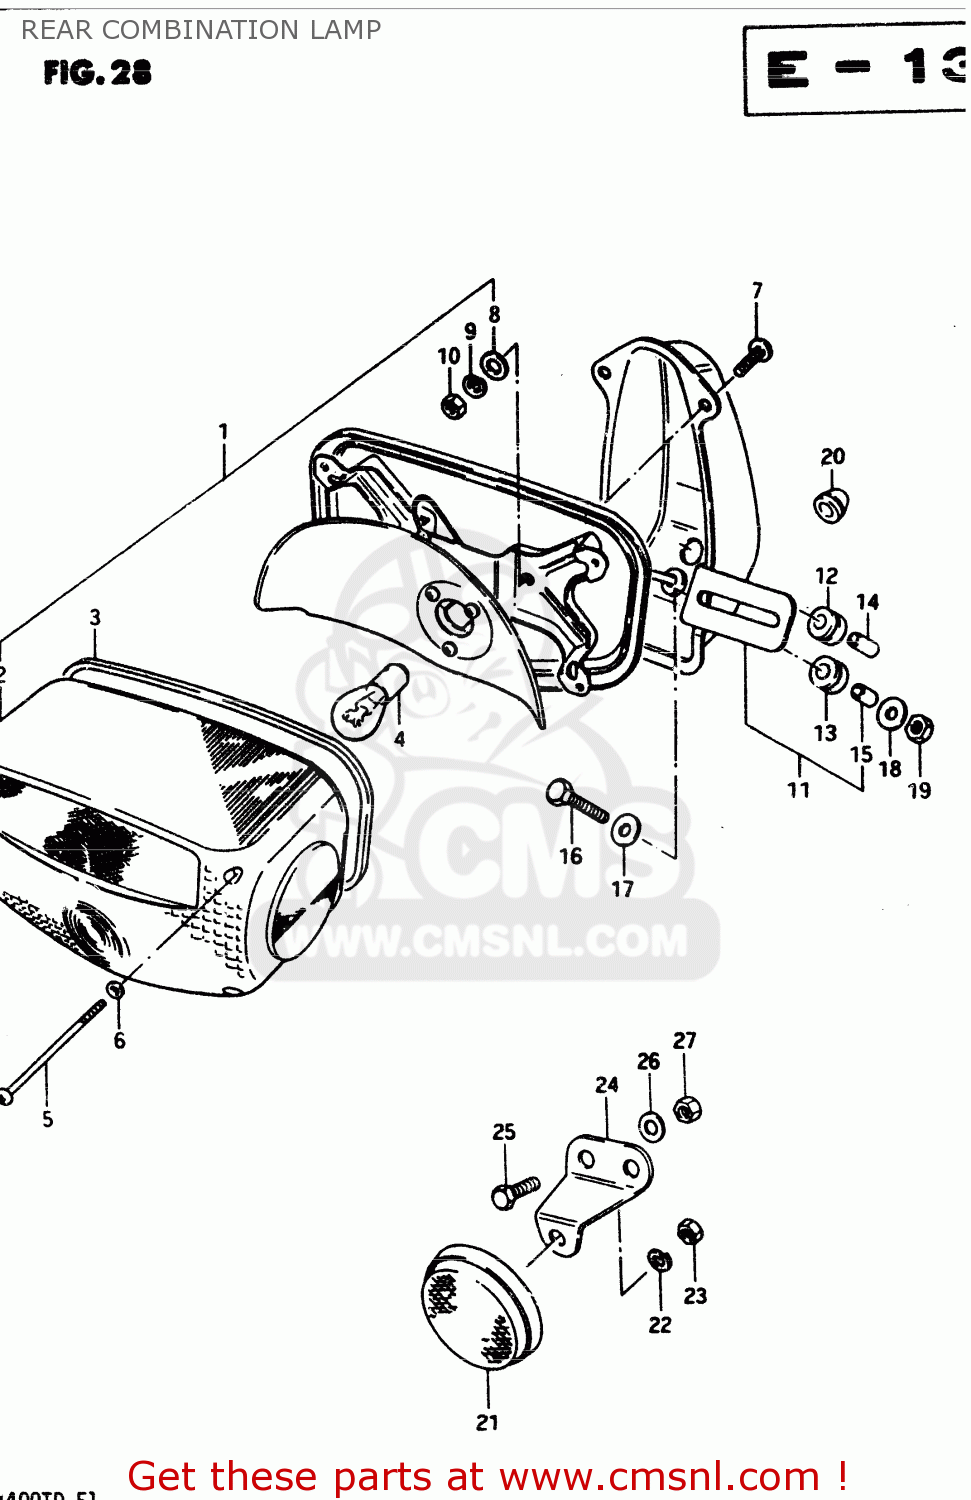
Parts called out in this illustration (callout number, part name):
1	LAMP UNIT, TAIL
2	LENS
3	GASKET (NAS)
4	BULB(12V21/5W)
5	SCREW (4X55)
6	GASKET (NAS)
7	SCREW 6X12
8	WASHER
9	LOCK WASHER
10	NUT
11	BRACKET ASSY
12	CUSHION
13	CUSHION,REAR COMBINATION LAMP
14	SPACER
15	SPACER,REAR COMBINATION LAMP
16	BOLT
17	WASHER (6.5X20X1.2)
18	WASHER
19	NUT
20	GROMMET
21	REFLEX REFLECTOR,RR
22	LOCK WASHER
23	NUT
24	BRACKET
25	BOLT
26	WASHER
27	NUT
